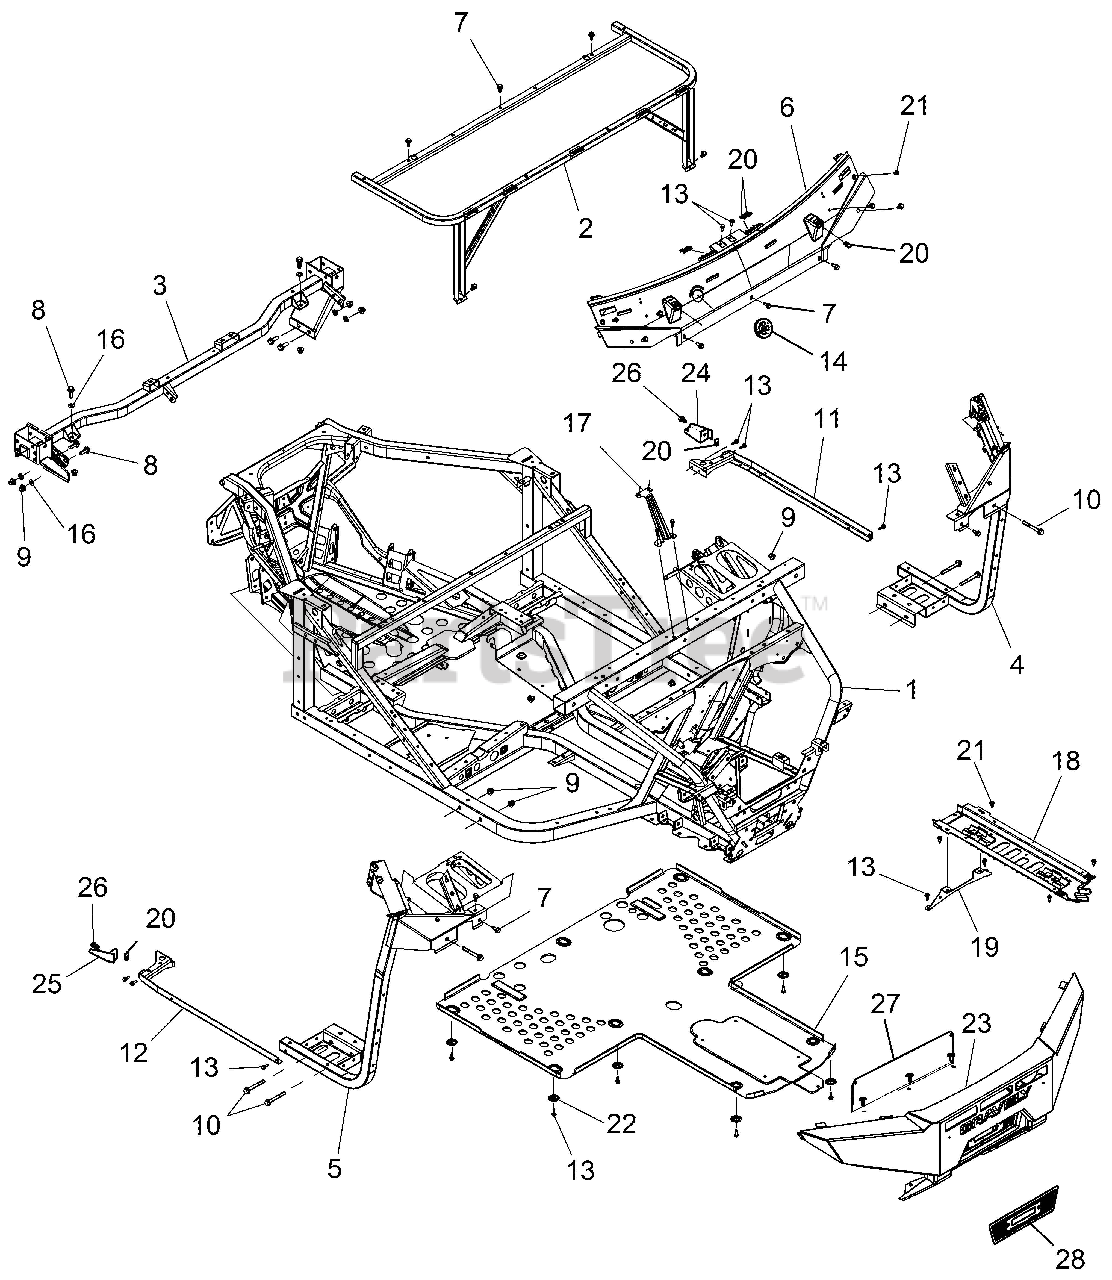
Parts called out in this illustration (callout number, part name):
1	FRAME, MAIN, MATTE BLACK
2	WELD-CAB/SEAT BASE,BLK
3	WELD-CAB SUPPORT,REAR,BLK
4	WELD-FLOOR SUPPORT,LH,BLK
5	WELD-FLOOR SUPPORT,RH,BLK
6	PLATE,WINDSHIELD MOUNT,LOW BLK
7	BOLT-M8X1.25X20,HXFLG,TAP/R-OD
8	SCR-HXFL-M10X1.25X30 8.8 ZOD
9	NUT-M10X1.25,FLG,NYLOC-OLIVE D
10	SCR-HXFL-M10X1.25X80 8.8 ZOD
11	WELD-ROCKER,LH,BLK
12	WELD-ROCKER,RH,BLK
13	SCR-M6X1.0X20,HXHD,FLG,TDFM,BL
14	GROMMET-ELEC,CAB,SLIT
15	PLATE-SKID,BLK
16	WASHER,3/8 FW
17	BRKT-PLATE,CTR,PIN MT,TTN
18	TRAY-ROUTING,BLK
19	BRKT-ROUTING TRAY,BLK
20	CLIP-U SPEED NUT
21	RIVET-TUFLOK,.315-.325X.787 (5
22	WASHER SKID PLATE
23	WELD-BUMPER,FRONT,ARIENS,M BLK
24	BRACKET,SUPPORT,ROCKER,LH BLCK
25	BRACKET,SUPPORT,ROCKER,RH BLCK
26	SCR-TXTH-M6X1.0X25 RIE
27	PLATE,GRAVELY RED
28	SCREEN-BUMPER,BLK
